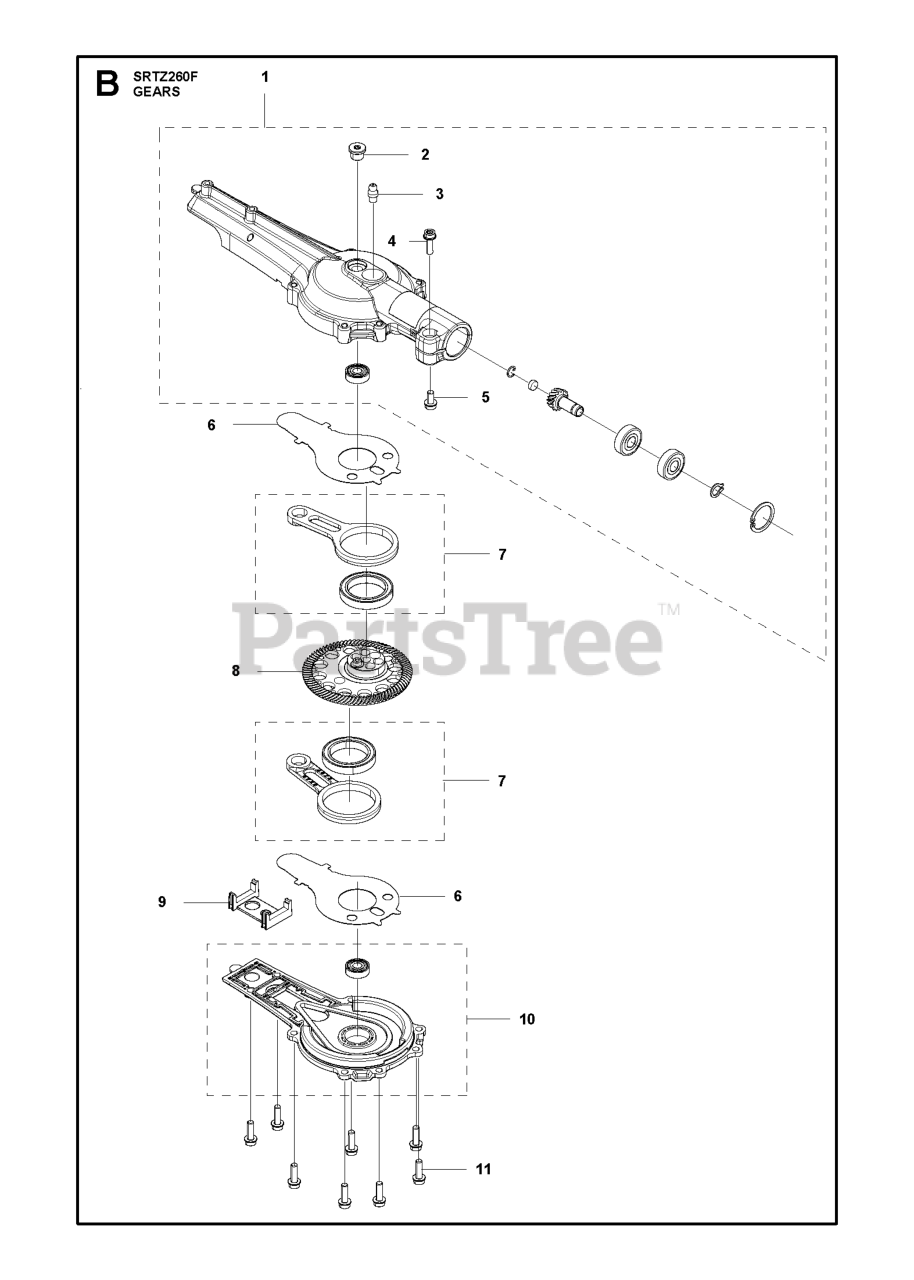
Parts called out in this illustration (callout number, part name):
1	GEAR HSG ASSY SPARE PART KIT
3	GREASE NIPPLE
5	SCREW ITXSCM
6	WEAR PLATE
8	GEAR WHEEL
